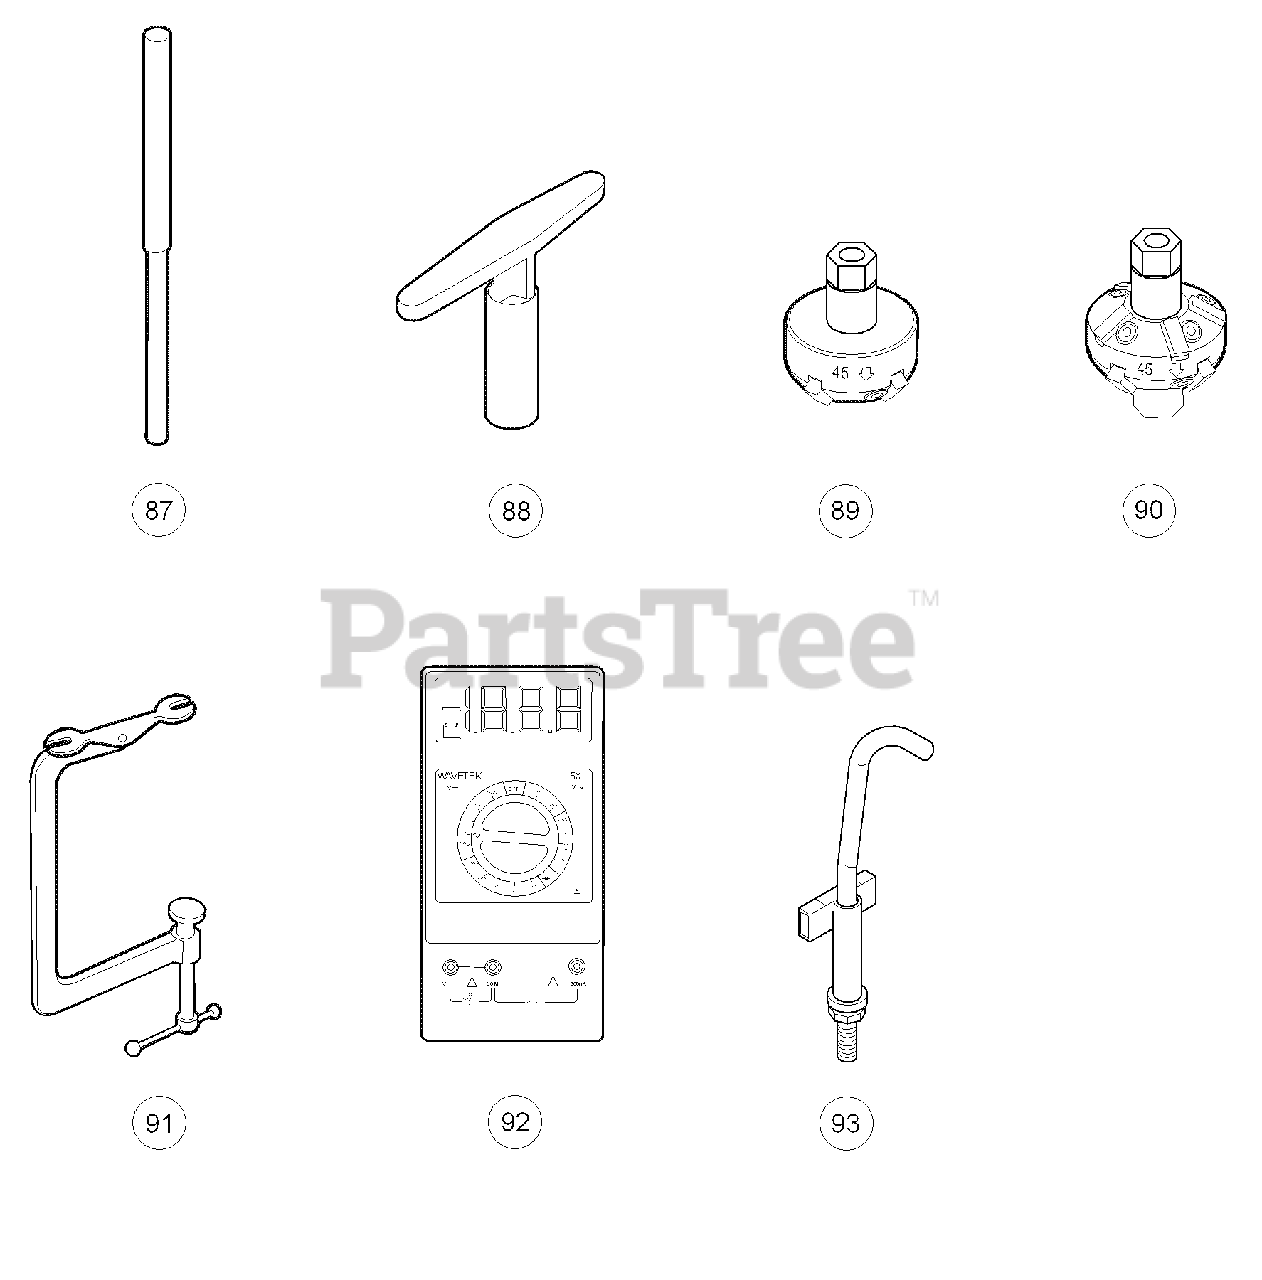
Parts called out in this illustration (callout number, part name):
86	Valve Seat Cutter Guide
87	Valve Seat Cutter T-Wrench
88	Valve Seat Cutter, 45°
89	Valve Seat Cutter, 45°/30°
90	Valve Spring Compressor
91	Volt Ohm Meter
92	Tool, Tensioning, Starter Generator
